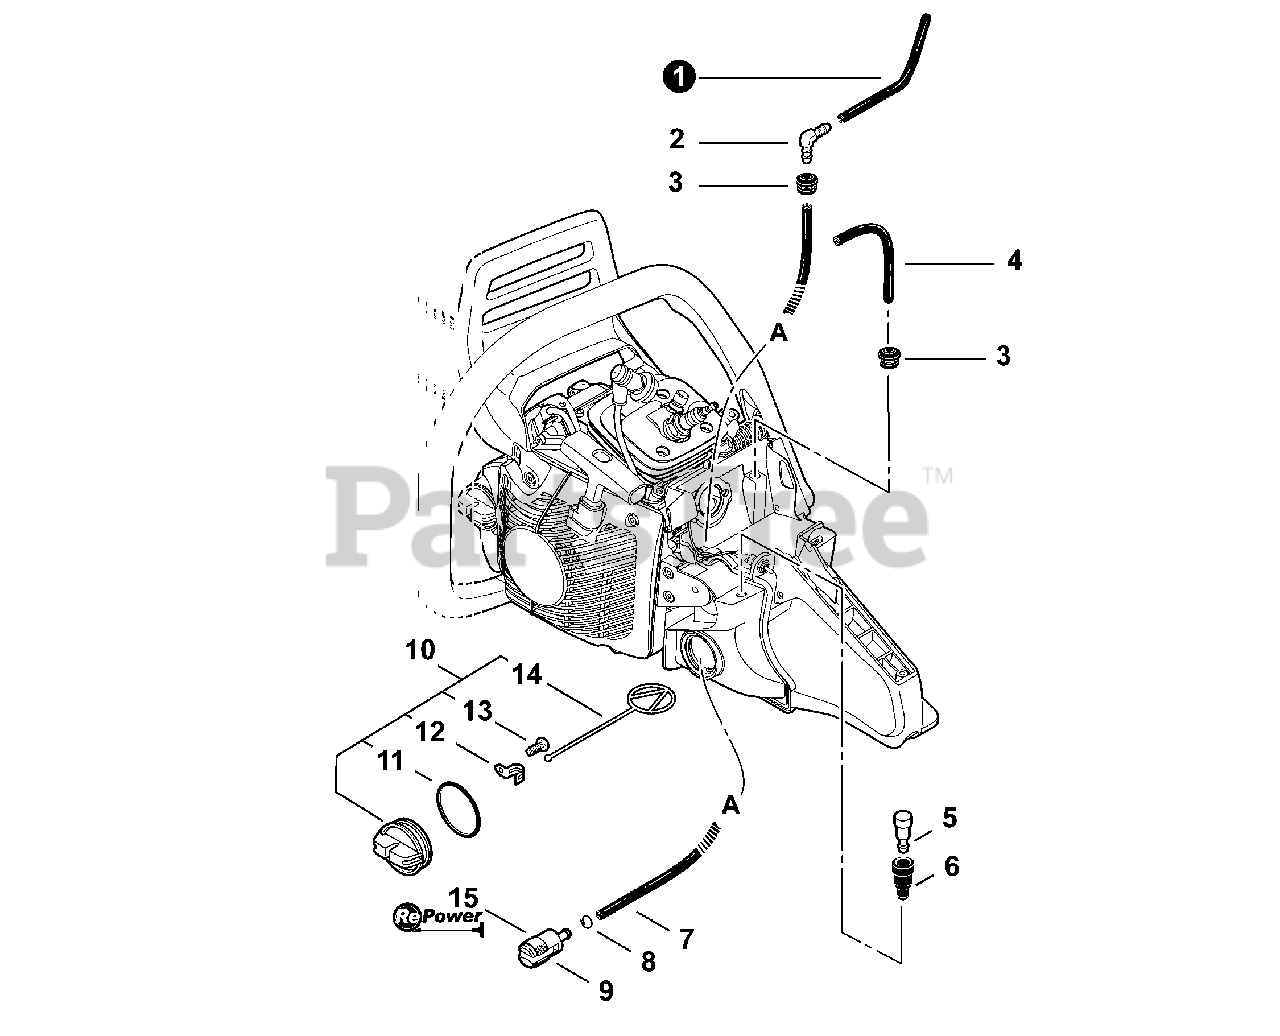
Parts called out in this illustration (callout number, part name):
1	PIPE, FUEL 3×6×135
2	CONNECTOR, PIPE 5.4
3	GROMMET
4	PIPE, IMPULSE 3×6(8)×160
5	VENT ASSY
6	GROMMET, VENT
7	PIPE, FUEL 3×5×120 BLACK
9	FILTER, FUEL
10	CAP ASSY, FUEL
11	O-RING 29
12	RETAINER, CONNECTOR
13	SCREW, TAPPING 3×8
14	CONNECTOR, CAP L= 60mm
15	TUNE-UP KIT - REPOWER
